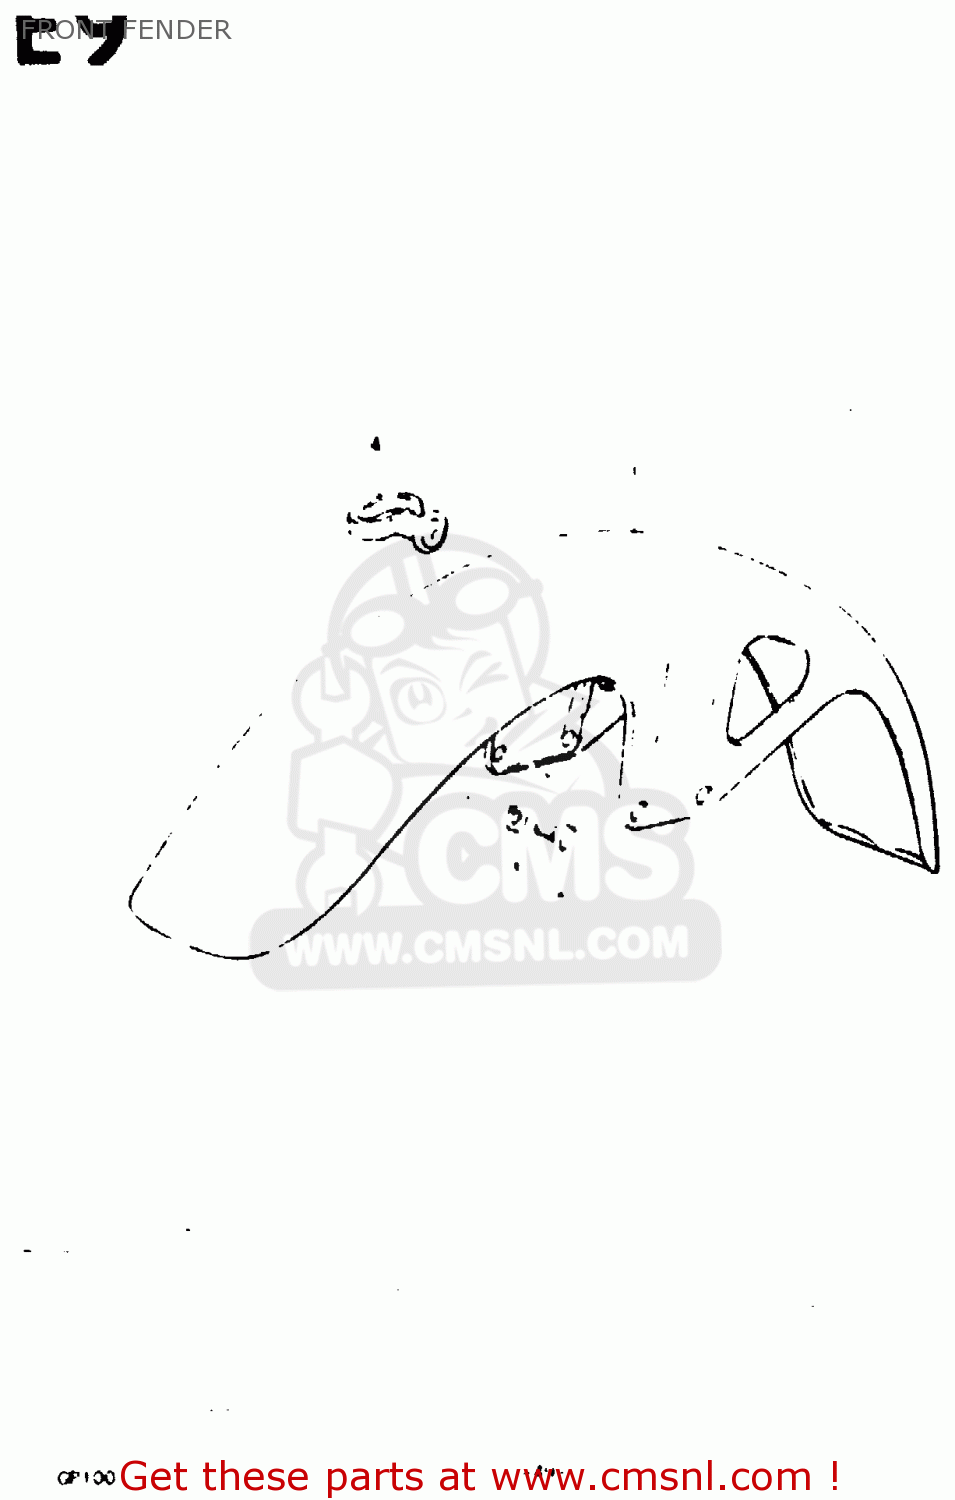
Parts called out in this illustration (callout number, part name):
1	FENDER, FRONT
2	BOLT
3	LOCK WASHER
4	GUIDE,CABLE
